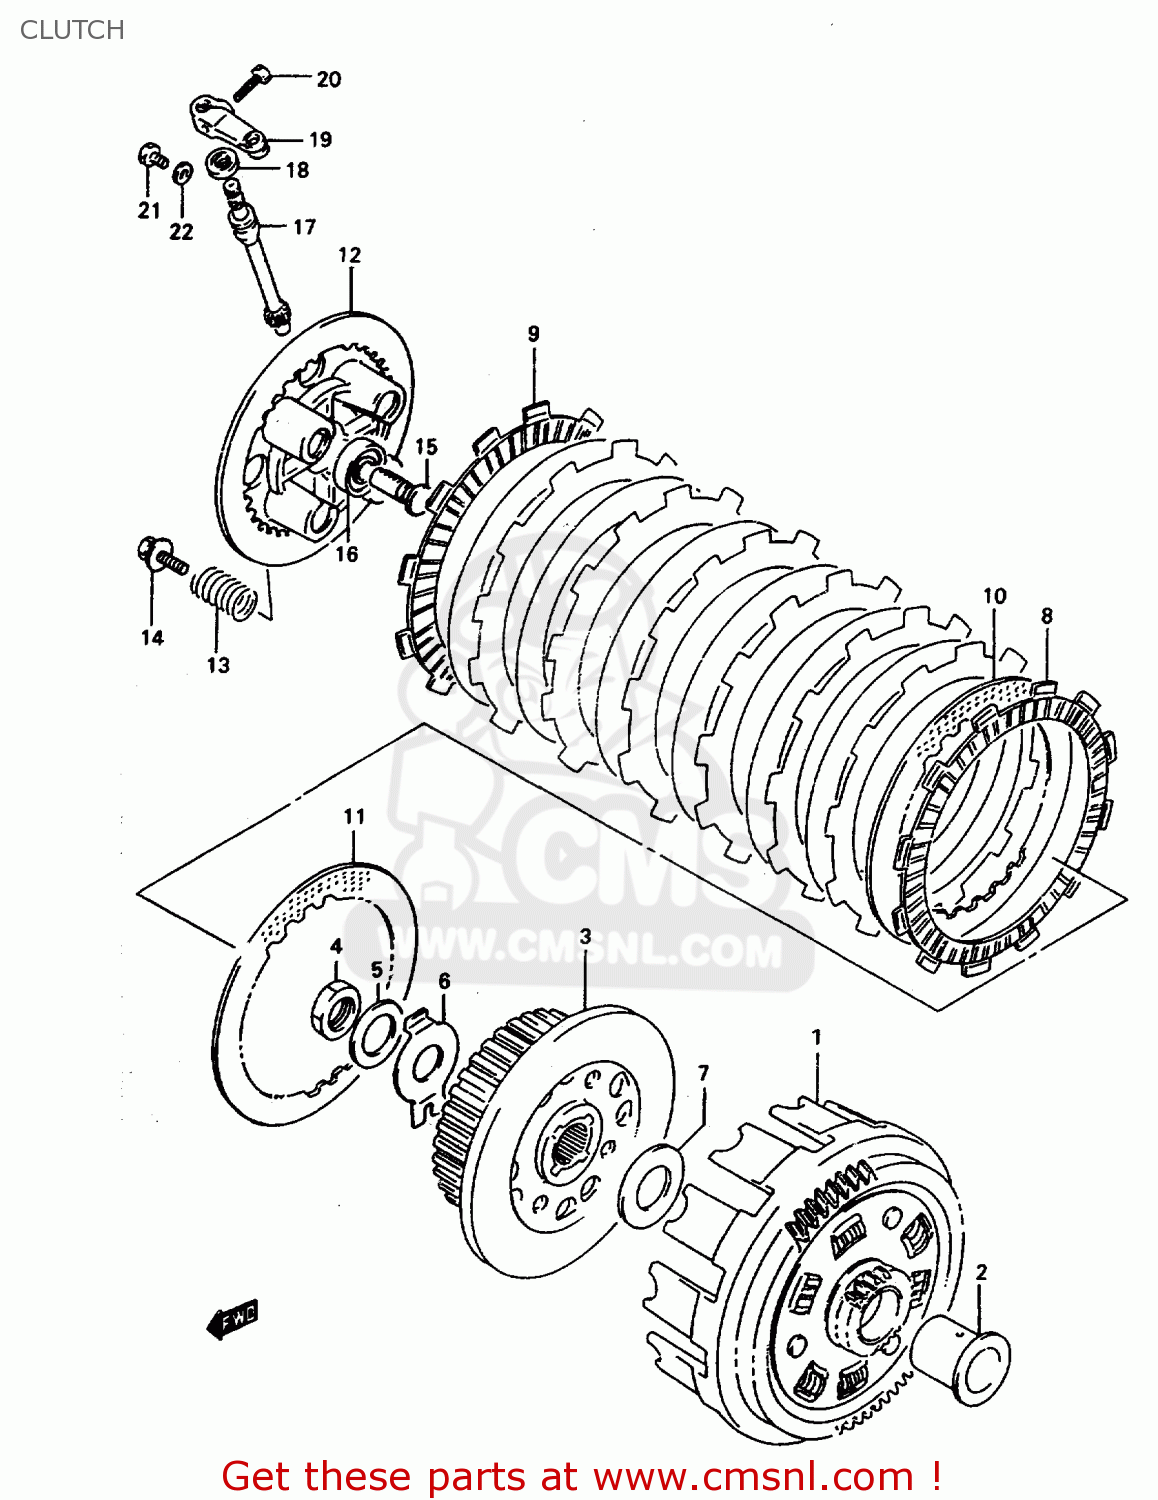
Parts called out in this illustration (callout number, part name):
1	GEAR ASSEMBLY,PRIMARY DRIVE
2	SPACER,PRIMARY DRIVEN GEAR
3	HUB,CLUTCH SLEEVE
4	NUT
5	WASHER
6	WASHER
7	WASHER(22X44X2)
8	PLATE,CLUTCH DRIVE (NAS)
9	PLATE,CLUTCH DRIVE (NAS)
10	PLATE,CLUTCH DRIVEN NO.1 (NAS)
11	PLATE,CLUTCH DRIVEN (NAS)
12	DISC,CLUTCH PRESSURE
13	SPRING
14	BOLT(6X16)
15	RACK,CLUTCH RELEASE
16	BEARING
17	PINION,CLUTCH RELEASE
18	SEAL,OIL(10X17X5)
19	ARM,CLUTCH RELEASE
20	BOLT
21	BOLT
22	GASKET(6.2X11X1).2 (NAS)
